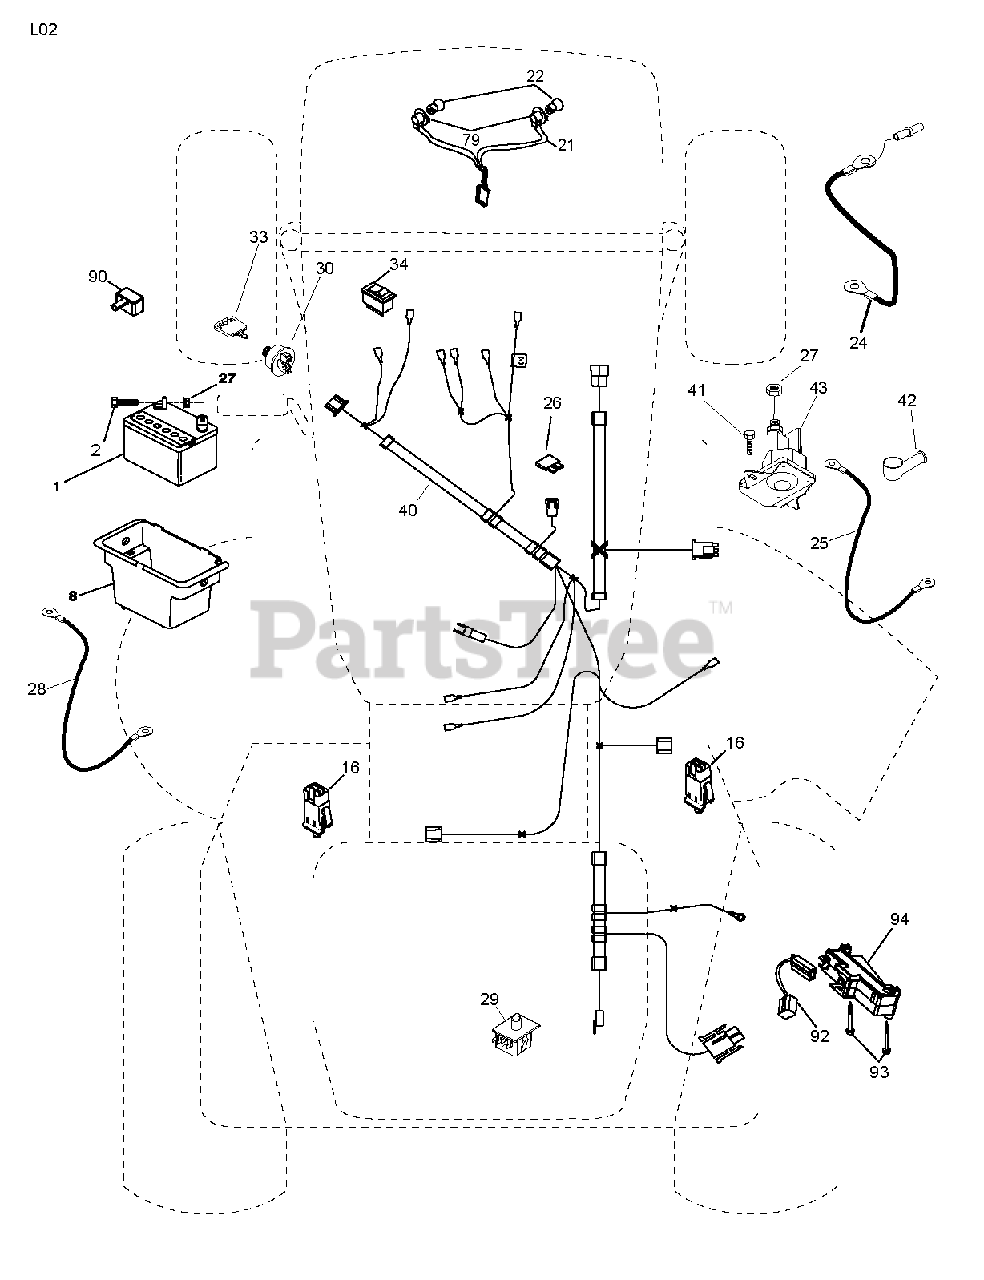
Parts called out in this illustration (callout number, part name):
1	REPL BY 532 12 38-99
8	BOX.BATTERY.FENDER
16	SWITCH INTERLOOK PUSH-IN
21	HARNESS ASSY LIGHT
22	LIGHTBULB
24	CABLE.GROUND.REAR.BTRY.8GA.44"
25	CABLE BATTERY 6 GA. 11" RED
26	FUSE 20AMP
27	NUT
28	CABLE GROUND 6 GA. 12" BLACK
29	SWITCH.SEAT.DP W/RAMPS
30	SWITCH.IGN.DELTA.W.LGH.ROS
33	KEY.CHAIN.BLISTER.PACK.GEN.INT
34	SWITCH LT
40	HARNESS.IGN.CABLE.REG.
42	TERMINAL COVER
43	SOLENOID.W/BRASS.PLUNG
79	BULB HOLDER ASM.
90	COVER.TERMINAL.BATTERY
92	HARNESS.PIGTAIL.CONSLE
93	SCREW.PLASTITE
94	MODULE.REVERSE.ROS
